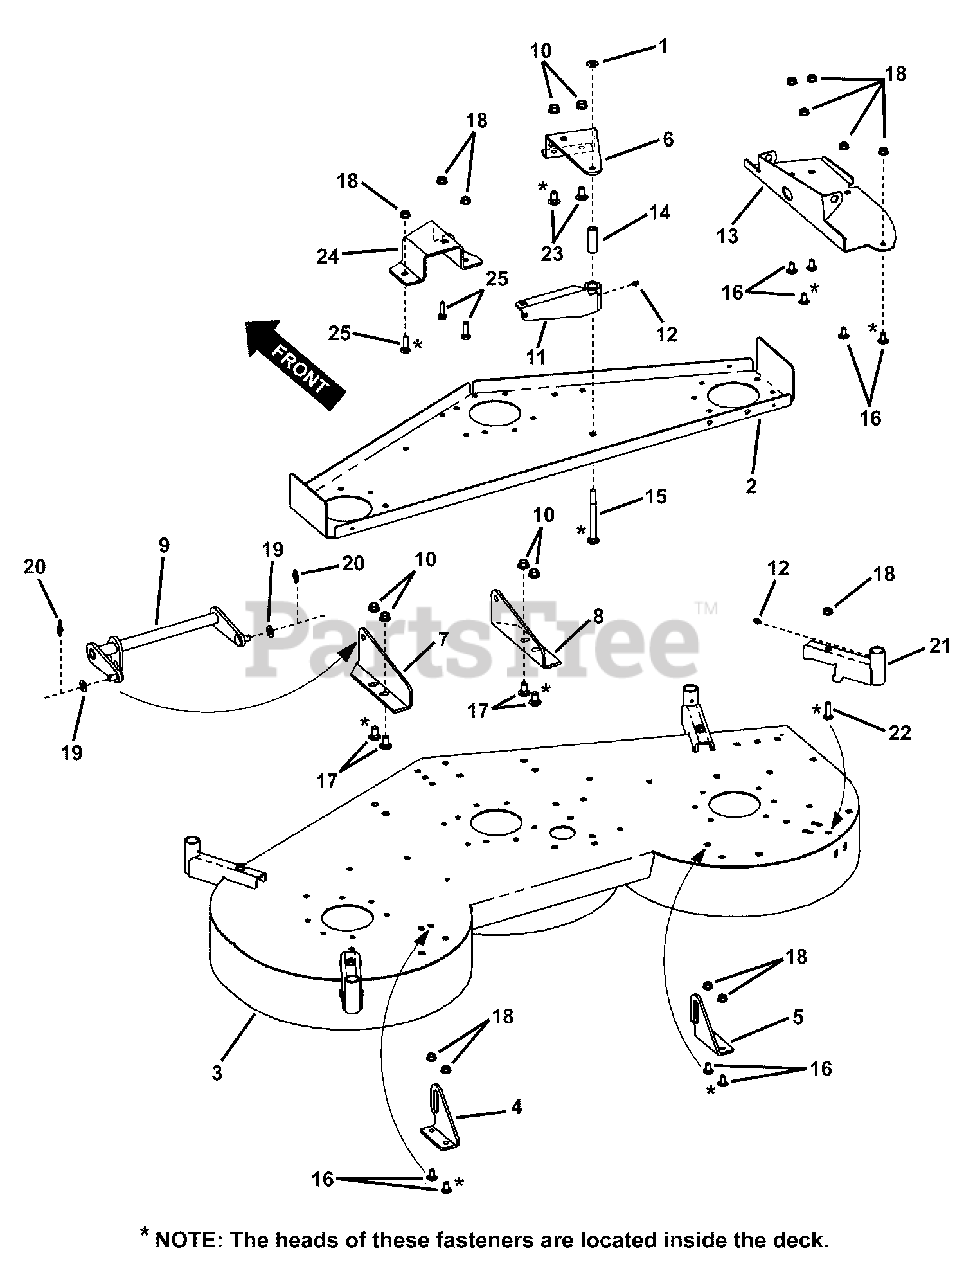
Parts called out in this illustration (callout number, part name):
1	RETAINER, 3/8" Bolt
2	STIFFENER, 48" Deck, HOZ
3	WELDMENT, 48" Deck
4	HANGER Rear R.H.
5	HANGER Rear L.H.
6	BRACKET, Pulley Mounting
7	BRACKET, Front Lift L.H.
8	BRACKET, Front Lift R.H.
9	WELDMENT, Front Lift, 48
10	NUT, 3/8-16 Hex Flange Lock
11	ASSEMBLY, Idler Arm/Lube Fitting
12	LUBE FITTING, Straight (press-fit for .187 dia. Hole)
13	BRACKET, Hinge, 48" Deck
14	SPACER, Pivot Collar, 48 HOZ
15	BOLT, 3/8-16 x 4" Square Neck Carriage, GR 5
16	BOLT, 5/16-18 x 5/8" Short Neck Carriage, GR 5
17	BOLT, 3/8-16 x 3/4" Short Neck Carriage, GR 5
18	NUT, 5/16-18 Hex Flange Lock, GR 5
19	WASHER, 3/8" SAE Flat
20	PIN, 3/8 Self Locking Cotter
21	WELDMENT, Caster Bracket
22	BOLT, 5/16-18X1-1/8" Short Neck Carriage, GR 5
23	BOLT, 3/8-16 x 3/4" Short Neck Carriage, GR 5
24	BRACKET, Stationary Idler
25	SCREW, 5/16-18 x 1" Hex Head Cap, GR 5
